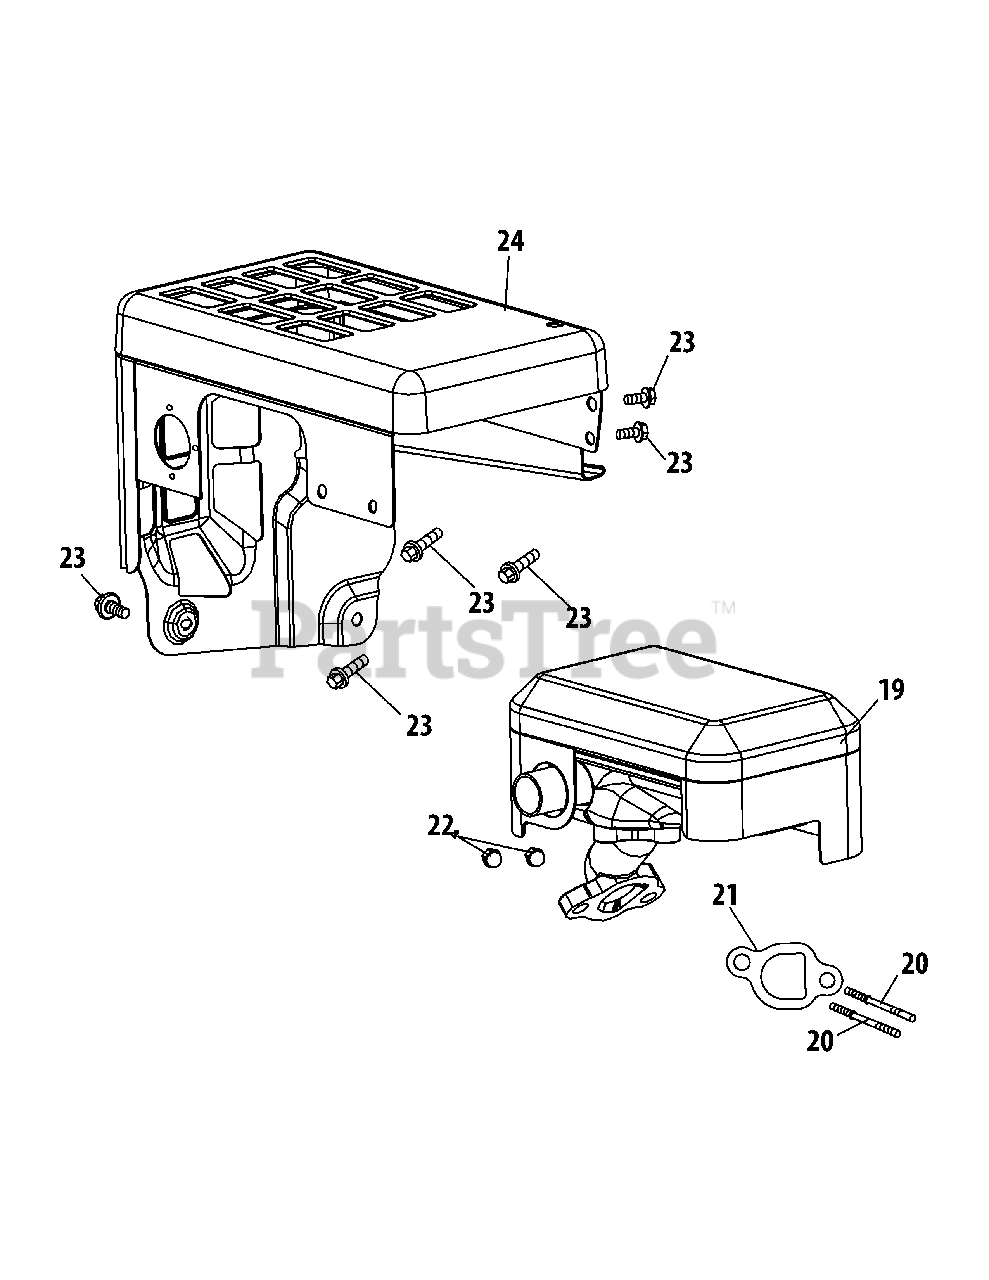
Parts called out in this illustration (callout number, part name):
19	Muffler Assembly
20	Stud M8×36
20	Muffler Stud Kit
21	Exhaust Pipe Gasket
23	Bolt M6×12
24	Muffler Shield
